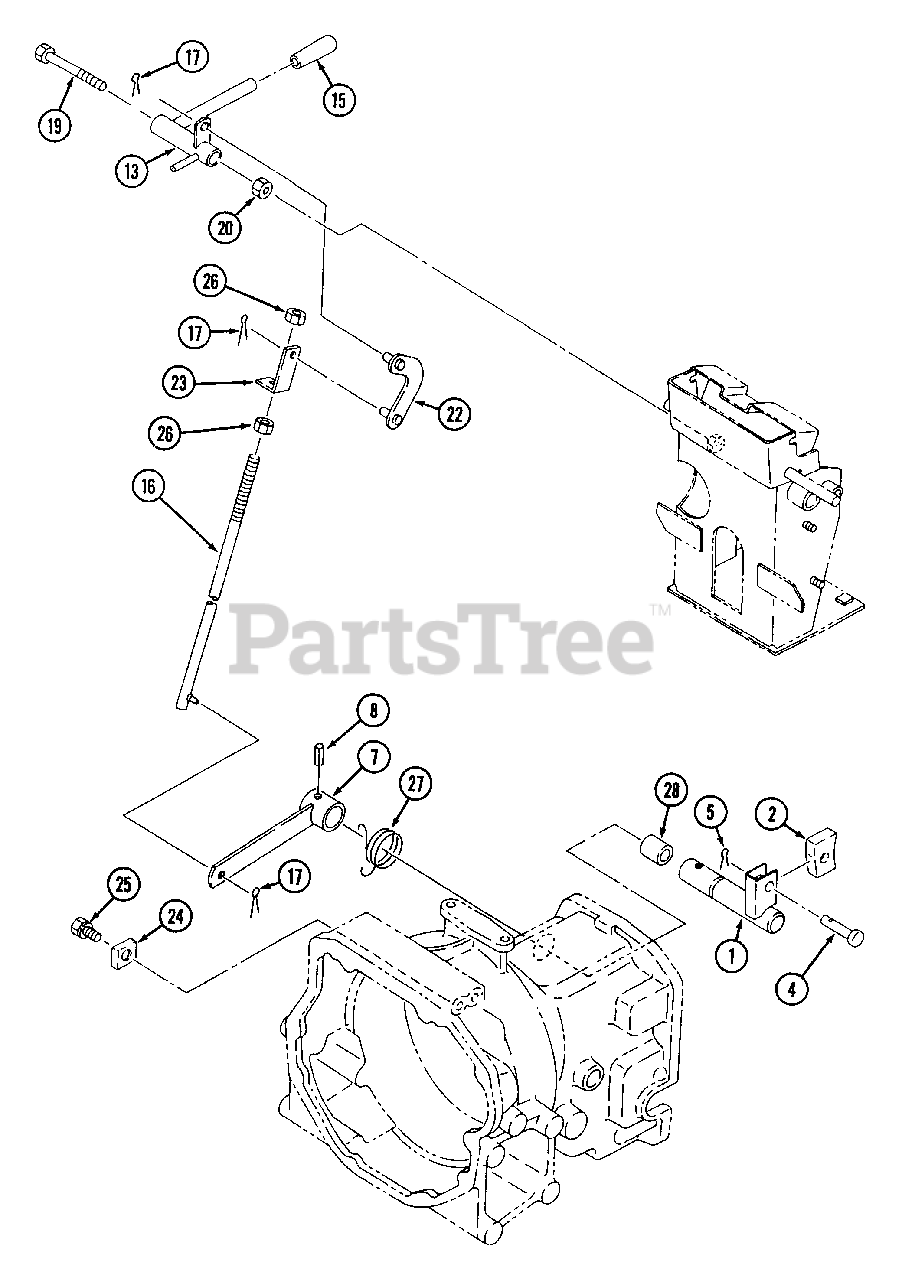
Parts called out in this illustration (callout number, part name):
5	Pin, Split
17	Pin, Split
25	Bolt w/Spring Washer
